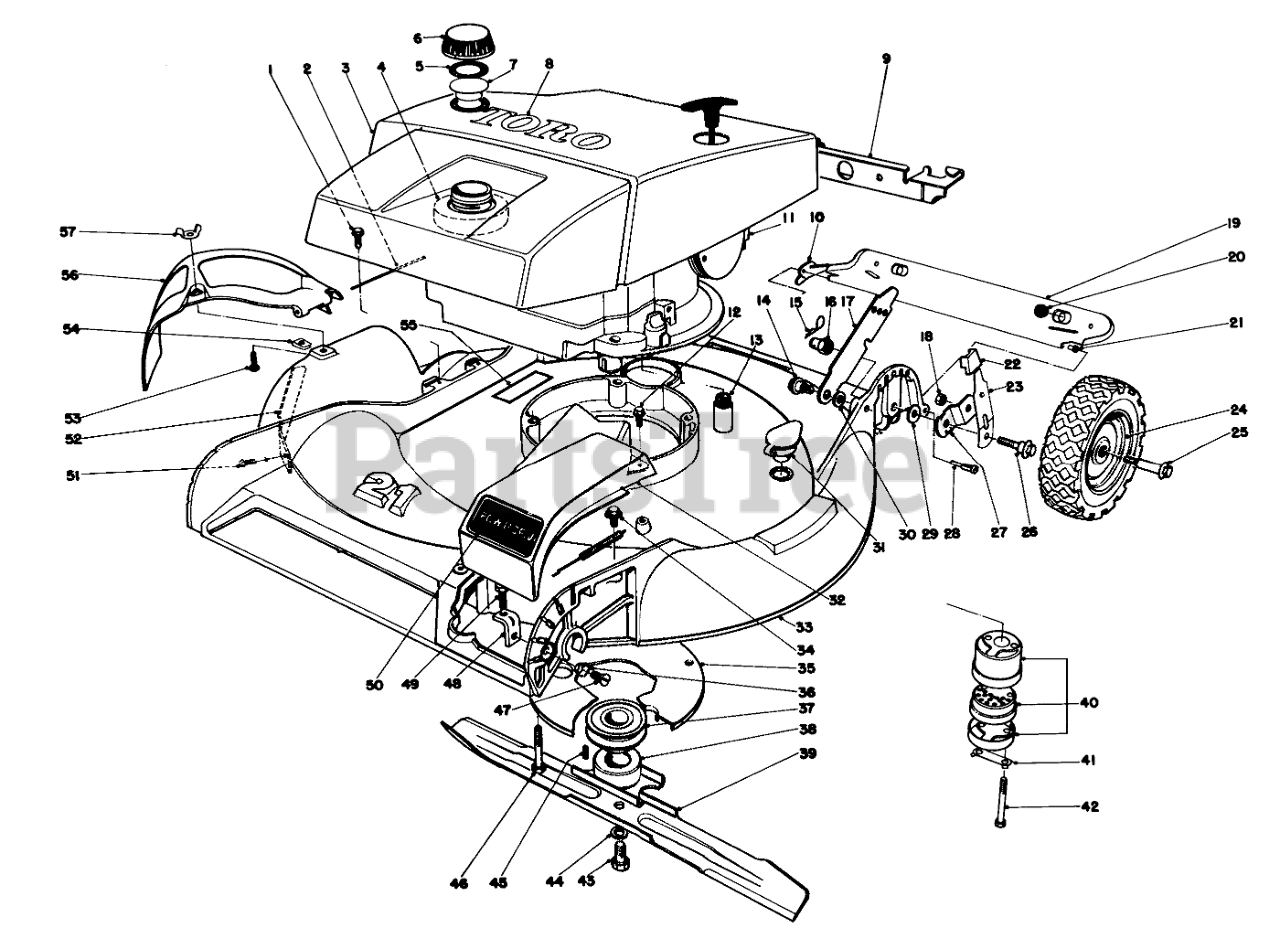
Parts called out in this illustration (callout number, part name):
1	SCREW
2	HINGE PIN
3	Shroud
4	FOAM PAD
5	GASKET
6	Gas Cap (Incl. Ref. #5 & 7)
7	GAS CAP BAFFLE
8	TORO LOGO DECAL
9	Shroud Bracket
10	Restraint R.H.
11	Engine
12	SCREW
13	Extension Oil Drain
14	SCREW-SHOULDER
15	PIN-COTTER, HAIR
16	HANDLE PIVOT NUT
17	Latch
18	Nut
19	Rear Safety Shield (Incl. Ref. #20-21)
20	SKID BUTTON
21	SAFTEY SHIELD BUSHING
22	Knob Arm
23	Spring Arm
24	Wheel Assembly
26	PIVOT SCREW
27	PIVOT ARM PLATED
28	SAFTEY SHIELD SCREW
29	WASHER-PIVOT
30	SPACER
31	WASHOUT PLUG
32	Guard, Belt
33	Housing
34	SCREW-HWHTF
35	Grass Guard
36	Lockwasher
37	Pulley
38	Blade Retailer
39	Blade
40	Muffler Assembly
41	CLIP - LOCKING
42	SCREW-HH
43	SPECIAL SCREW
44	WASHER-LOCK
45	Key Square
46	3/8-16 X 2-3/4 CAPSCR
48	ADJ BRACKET
49	SCREW-HH
50	Decal Power Drive
51	SCREW-HWH
52	Bar Safety
55	Decal
56	Deflector
57	NUT-WING SPECL
